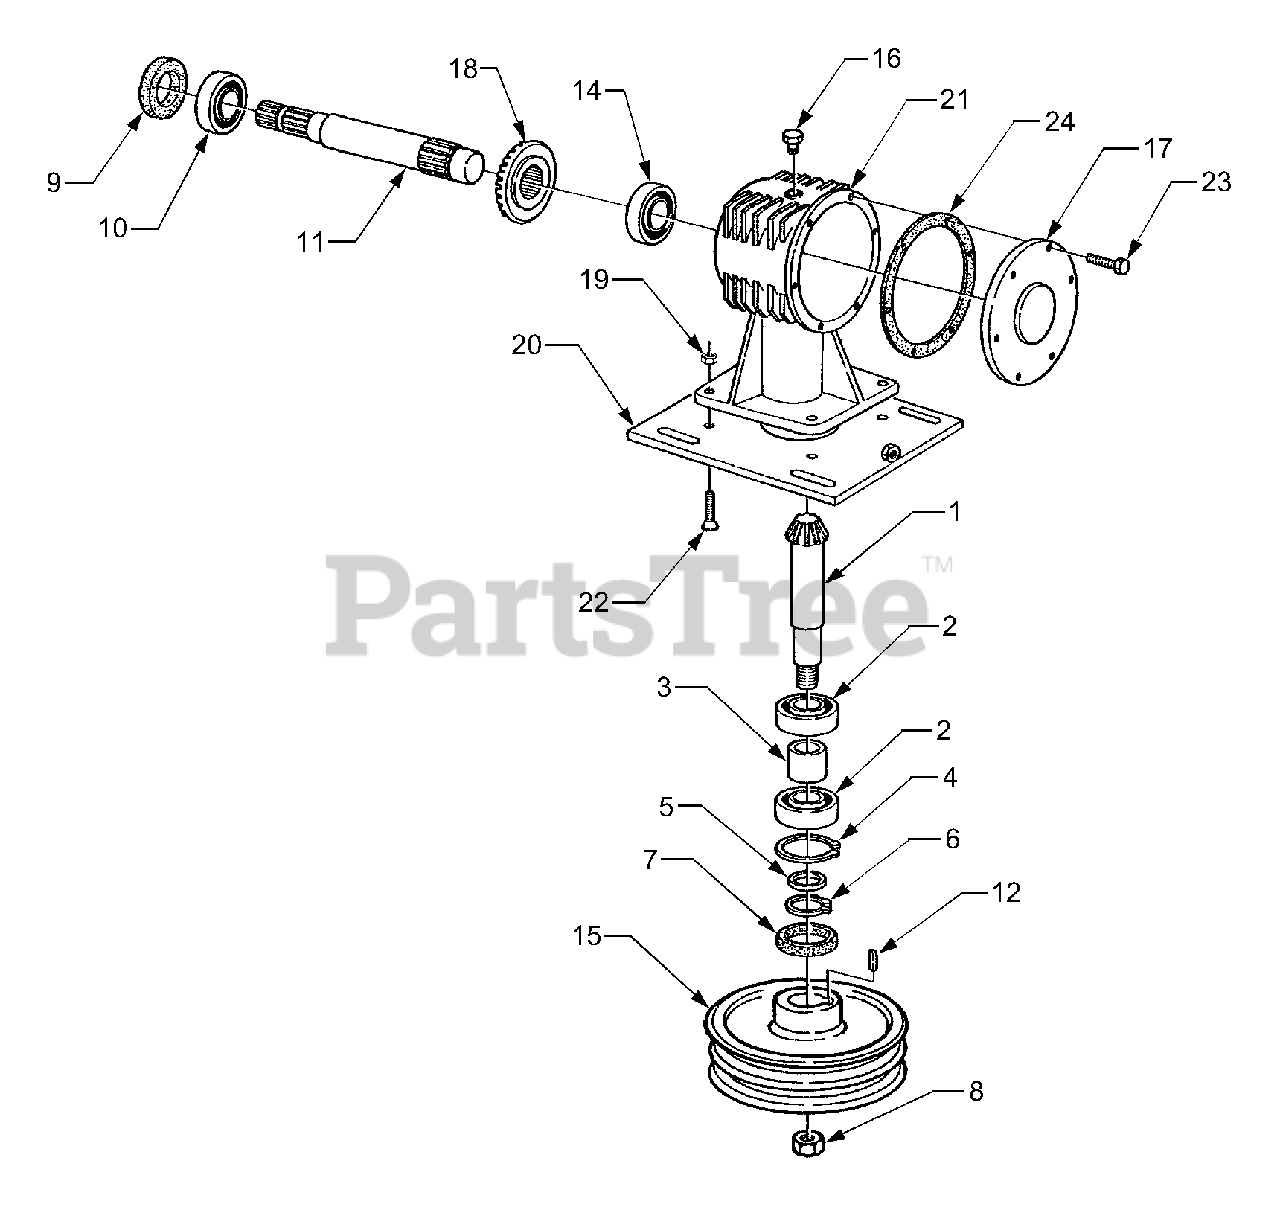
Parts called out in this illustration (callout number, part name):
1	Pinion Gear
4	Snap Ring (Inner)
5	Spacer Washer
6	Snap Ring, (Outer)
11	Input Shaft
16	Breather, Cap
17	Gearbox Cover
20	Gearbox Support Plate
21	Gearbox Housing
22	Bolt, 12mm x 45
23	Bolt, 10mm x 20
24	Gasket .012 Thk
